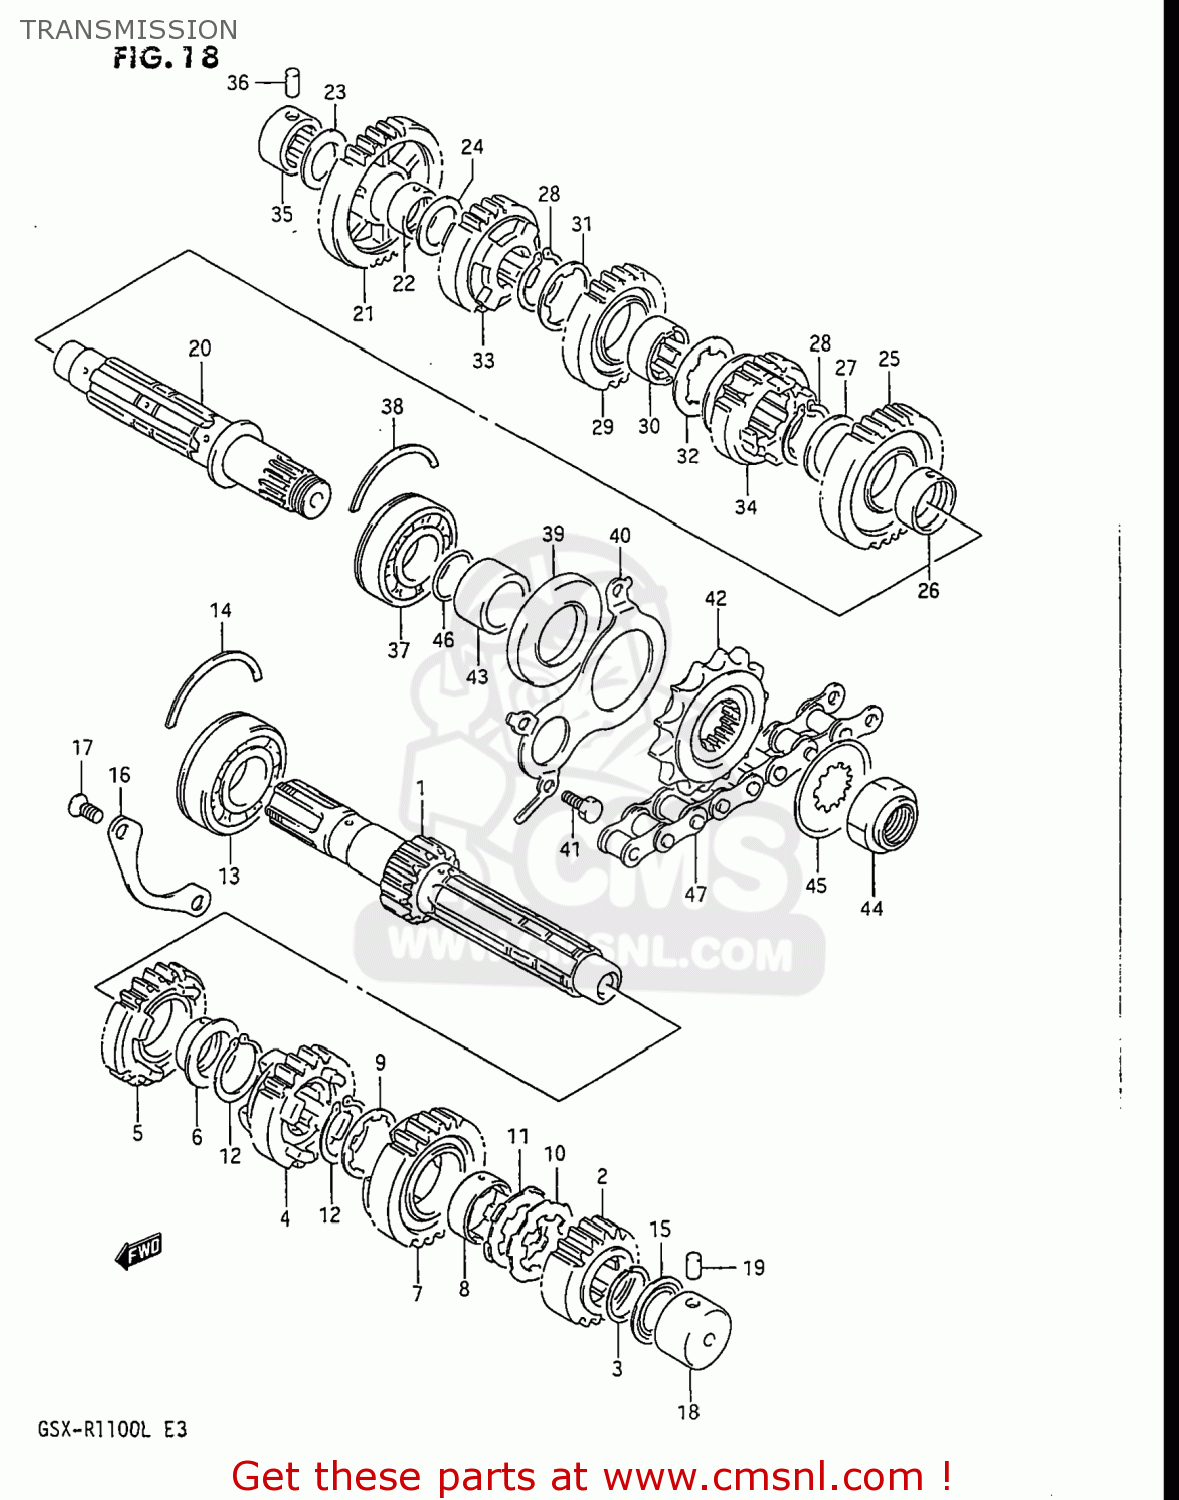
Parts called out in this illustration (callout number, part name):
1	SHAFT,COUNTER
2	GEAR,2ND DRIVE(NT:19)
3	CIRCLIP
4	GEAR,THIRD DRIVE (NT:20)
5	GEAR,FOURTH DRIVE (NT:22)
6	BUSHING
7	GEAR,FIFTH DRIVE (NT:23)
8	BUSH,5TH DRIVE GEAR
9	WASHER,LOCK
10	WASHER,LOCK
11	WASHER
12	RING,SNAP
13	BEARING(25X62X17)
14	C-RING
15	SEAL,OIL(20X31.2X2.7)
16	RETAINER,CNTR SHAFT BEARING
17	SCREW
18	BEARING(20X34X17.5)
19	PIN
20	SHAFT,DRIVE
21	GEAR,FIRST DRIVEN
22	BUSHING
23	WASHER
24	WASHER
25	GEAR,SECOND DRIVEN
26	BUSH(28X32X11)
27	WASHER
28	CIRCLIP
29	GEAR,THIRD DRIVEN
30	BUSHING,THIRD DRIVEN GEAR
31	WASHER,LOCK
32	WASHER,LOCK
33	GEAR,FOURTH DRIVEN (NT:23)
34	GEAR,FIFTH DRIVEN
35	BEARING(20X34X20)
36	PIN
37	BEARING(25X62X19)
38	C-RING
39	SEAL,OIL(34X62X6)
40	RETAINER,DRIVE SHAFT OIL SEAL
41	BOLT
42	SPROCKET,ENGINE(15T)
43	SPACER(25X34X22.7)
44	NUT
45	WASHER,LOCK
46	O RING(D:1,ID:24.5)
47	CHAIN,DRIVE(118LE)
